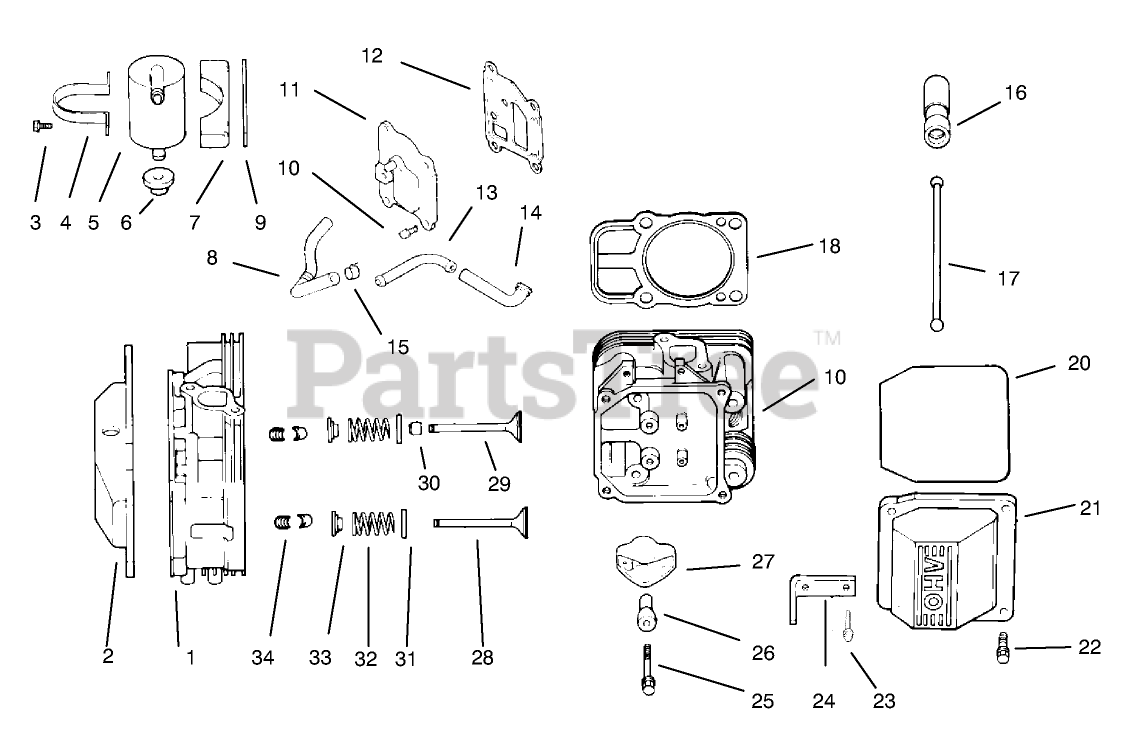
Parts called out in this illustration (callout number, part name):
1	Head ASM-#1 Cylinder (Only On: 72103, 72083)
2	Cover-Rocker (Only On: 72103)
3	Kit-Breather INCL 4 (Only On: 72103)
4	Grommet-Rubber (Only On: 72103)
5	Cover-Breather (Only On: 72103)
7	Hose-Breather (Only On: 72103)
8	Kit-Retainer
9	Cap-Valve Spring
10	Spring-Valve
11	Retainer-Spring
12	Valve-Exhaust
13	Valve-Intake
14	Seal-Valve Stem
15	Fitting (Only On: 72103)
16	Hose-Breather (Only On: 72103)
17	Lifter-Valve
18	Rod-Push (Only On: 72103,72083)
19	Gasket-Cylinder Head
20	Head ASM-#2 Cylinder (Only On: 72103, 72083)
21	Arm-Rocker (Only On: 72103,72083)
22	Ball-Rocker Pivot
24	Cover-Rocker (Only On: 72103)
25	Screw
27	Strap-Lifting
